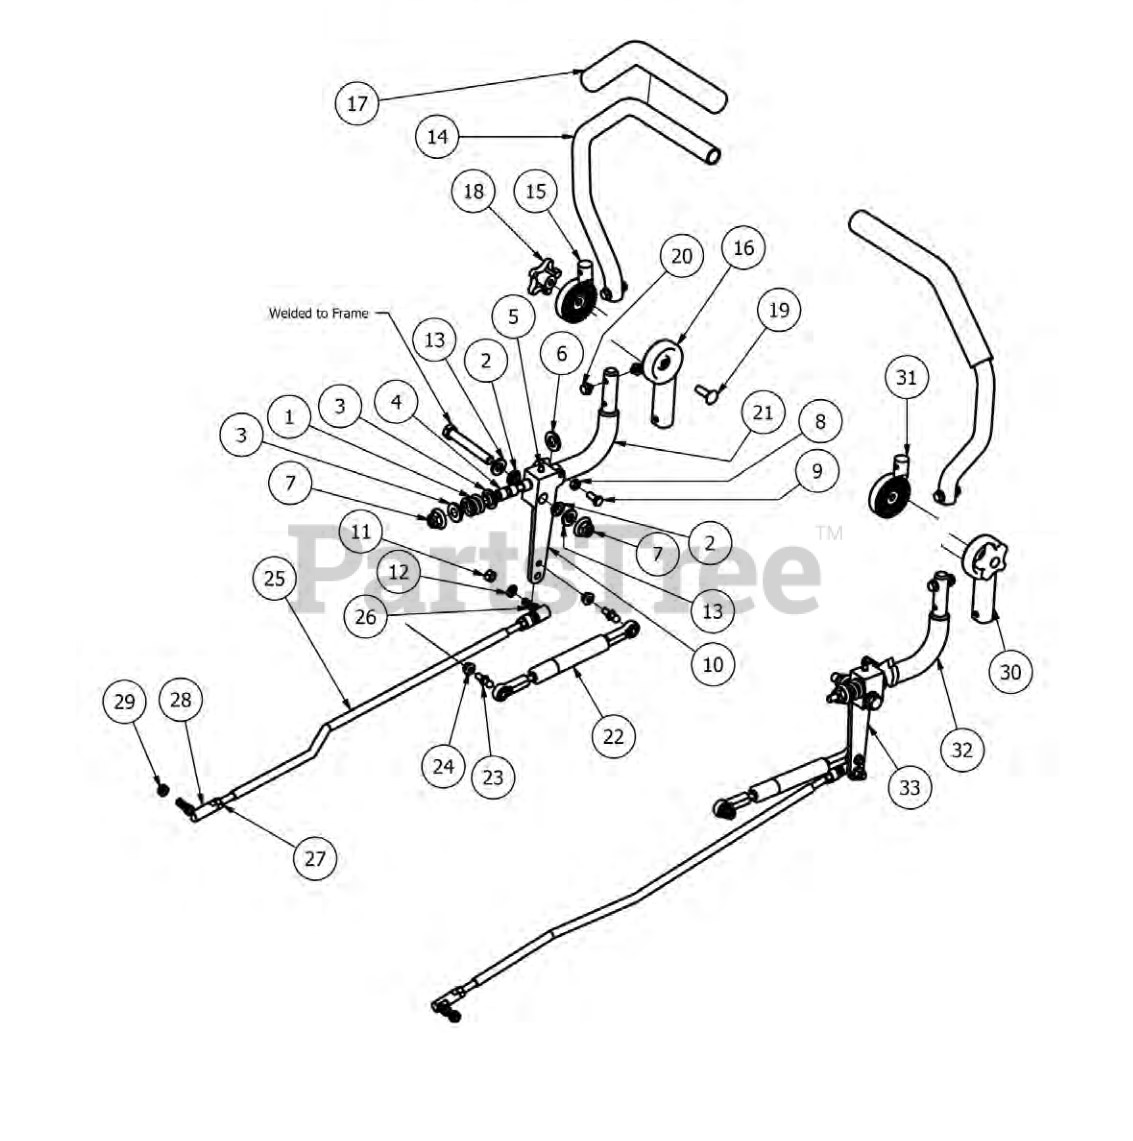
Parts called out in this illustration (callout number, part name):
1	Drive Lever Spring
2	Bushing for 2012 Drive Arms
3	.515 ID Nylon Shoulder Washer
4	.507 ID Nylon Bushing
5	1/4" Drive in Grease Fitting
6	.635 ID Plastic Washer
7	1/2-13 Nylon Flange Nut-Orange
9	5/16" x 3/4" Hex Bolt
10	Drive Arm Lever Housing (Left)
11	3/8" Fine Threaded Jam Nut
12	3/8" Lock Washer
13	.505x1x.125 Oil Impregnated washer
14	Upper Tube-Adjustable Steering
15	Upper adjuster-Steering Arm- Left
16	Lower Adjuster -Steering Arm- Left
17	Rubber Grip
18	3/4 OD x 1/2 ID x 3\4 Length
19	3/8" x 1 1/4" Carriage Bolt
20	5/16-18 1/2 HWH Bolt-Steering
21	Steering Arm Elbow - Left
23	10mm Damper Ball Stud-Steering
24	5/16" Flange Nut
25	outlaw XP Push Rod
26	Quick Release Ball Joint
27	3/8" Fine Threaded Jam Nut
28	3/8-24 Ball Joint
29	3/8-24 Nylon Insert jam locknut
30	Lower Adjuster - Steering Arm- Right
31	Upper Adjust Steering Arm- Right
32	Steering Arm Elbow - Right
33	Drive Arm Lever Housing Right
